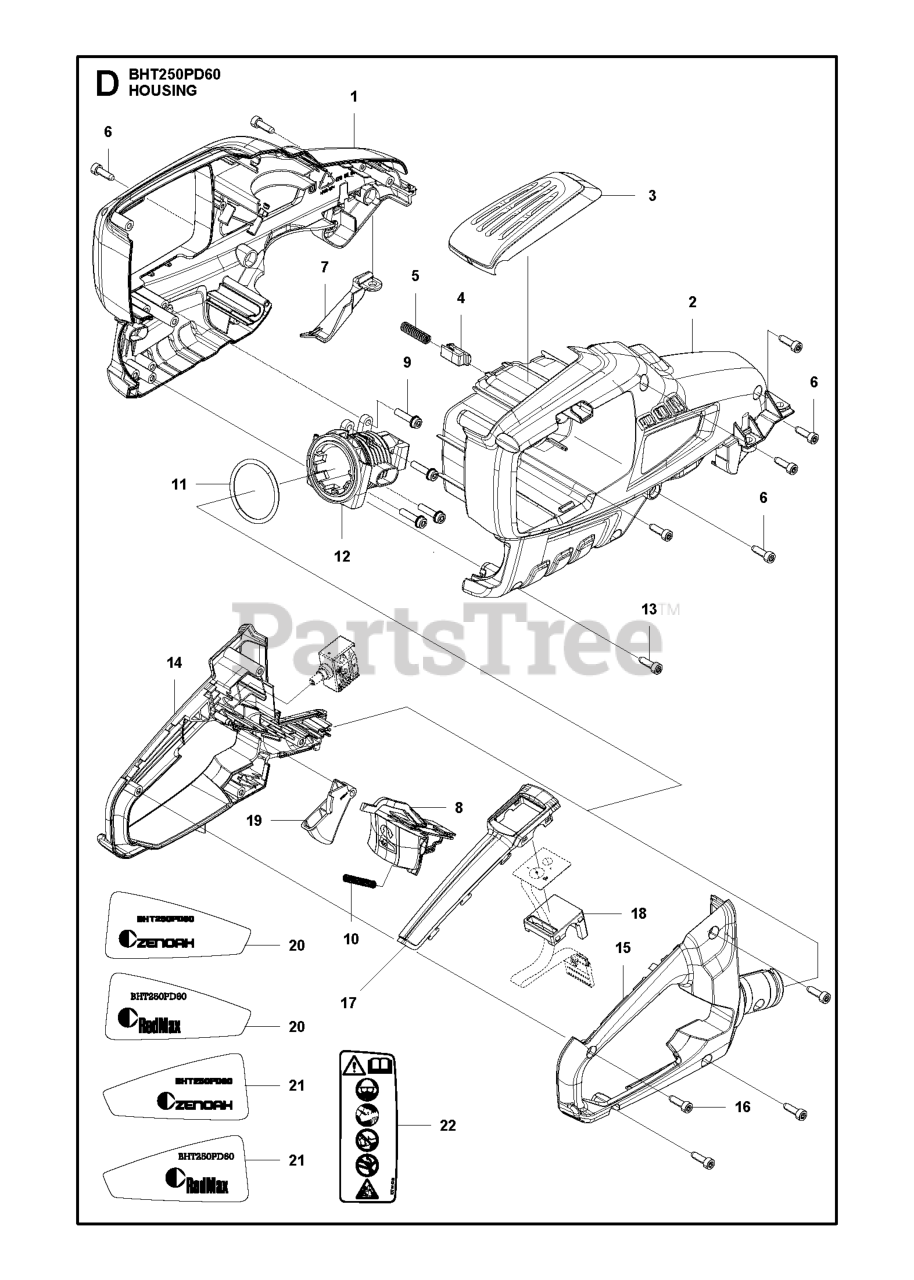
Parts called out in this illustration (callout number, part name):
1	CHASSIS LEFT ZENOAH/REDMAX - R
2	CHASSIS RIGHT ZENOAH/REDMAX -
3	COVER CHASSIS ZENOAH/REDMAX
4	PUSH BUTTON
5	SPRING PUSH OUT
7	COVER WIRING BLACK
8	LOCKING BUTTON ZENOAH/REDMAX
9	SCREW IHSCFT
10	RECOIL SPRING RECOIL SPRING RE
11	O-RING
12	HANDLE HOLDER BLACK
14	REAR HANDLE LEFT BLACK
15	REAR HANDLE RIGHT BLACK
17	FRAME KEYPAD BLACK
18	BRACKET KEYPAD
19	THROTTLE CONTROL ZENOAH/REDMA
20	DECAL PRODUCT DECAL REDMAX BHT
21	DECAL PRODUCT DECAL REDMAX BH
